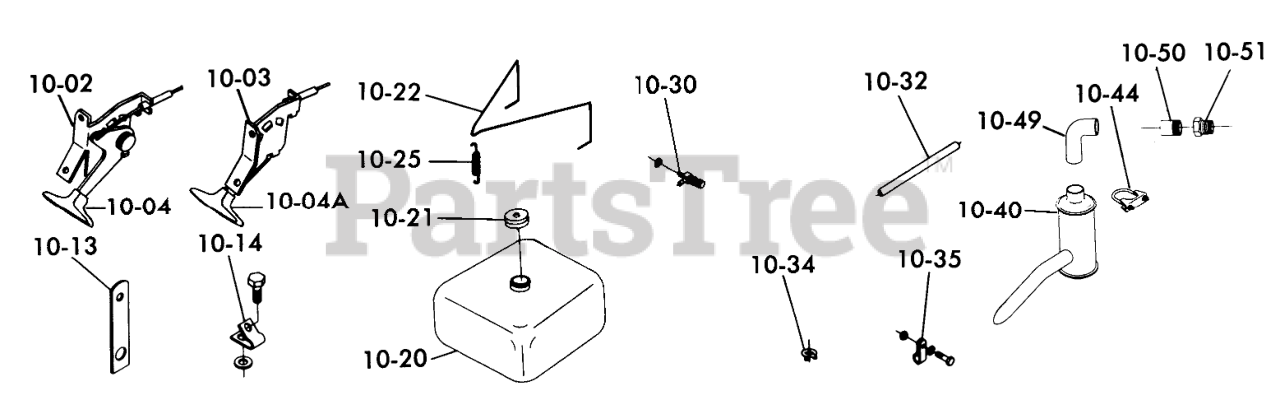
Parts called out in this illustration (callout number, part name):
10-02	Choke Control
10-03	THROTTLE CONTROL
10-03	SCREW
10-03	#10-24 Kep-Nut
10-04	KNOB-CHOKE
10-04A	KNOB-THROTTLE
10-13	Strap
10-14	THROTTLE CONTROL CLP
10-14	Clip
10-14	Screw
10-14	Special Nut
10-14	Bolt
10-14	Nut
10-20	Bushing
10-21	Cap
10-22	HOLD DOWN WIRE
10-25	CLUTCH SPRING
10-30	VALVE-FUEL
10-30	BUSHING
10-32	Fuel Hose
10-34	Clamp
10-35	CLAMP-HOSE
10-35	Bolt
10-35	WASHER 5/16 SAE
10-35	Nut
10-40	MUFFLER
10-44	ASSY-MUFFLER CLAMP
10-49	MUFFLER INLET TUBE
10-50	NIPPLE
10-51	REDUCER 1 1/4-1
